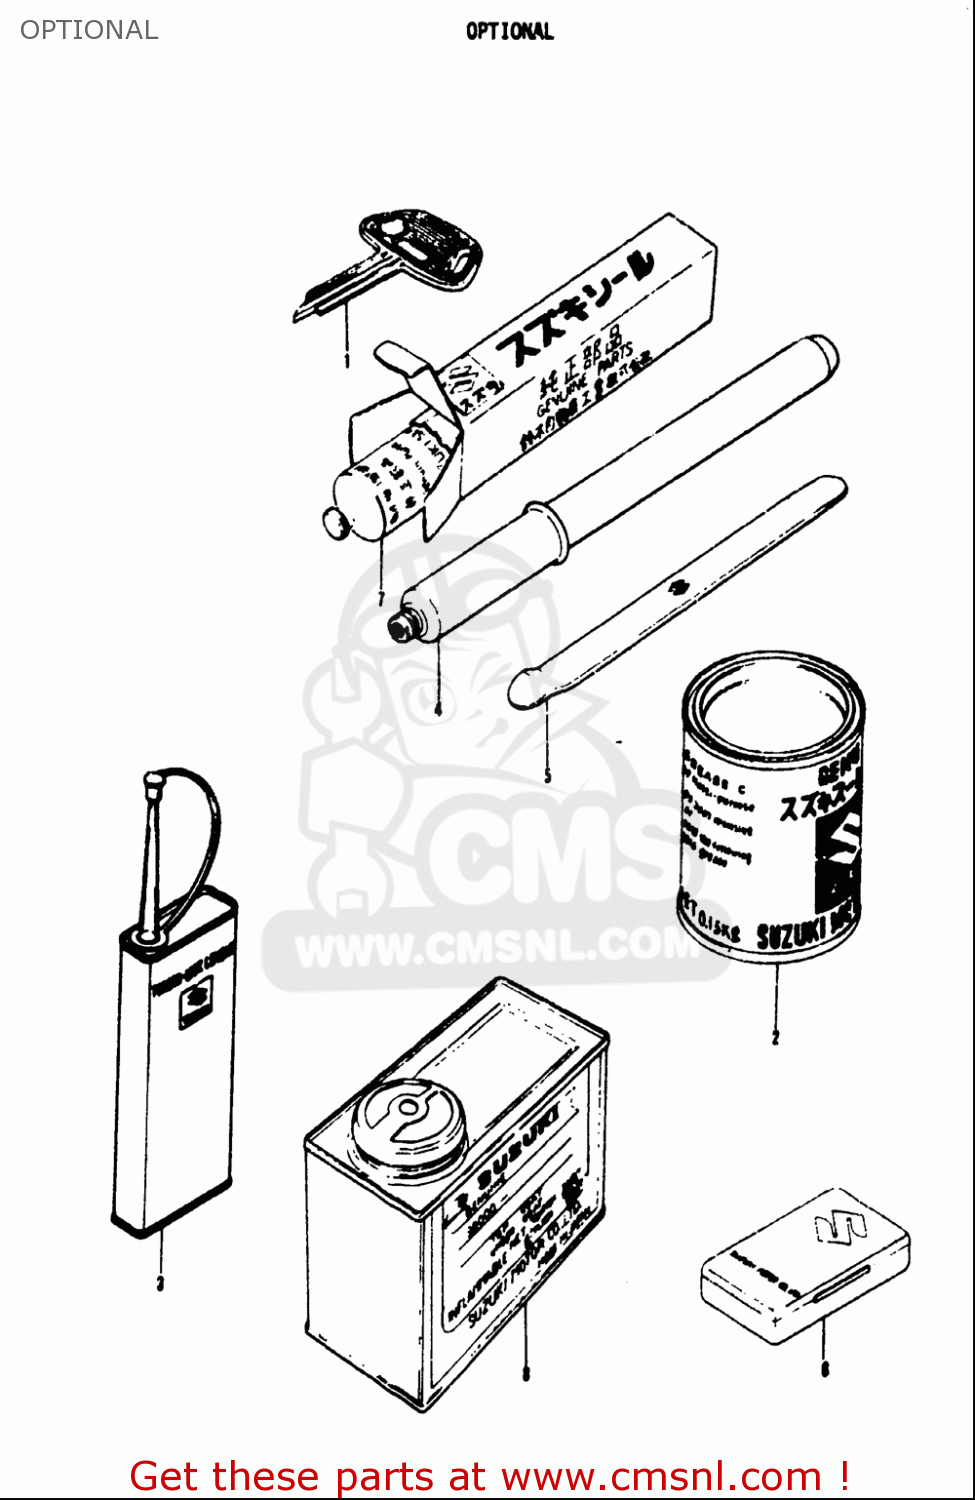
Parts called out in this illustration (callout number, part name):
2	GREASE(C)EP2 LITHIUM 150G
3	THREAD LOCK NO.1401 CLEAR 200G
5	LEVER,TIRE
